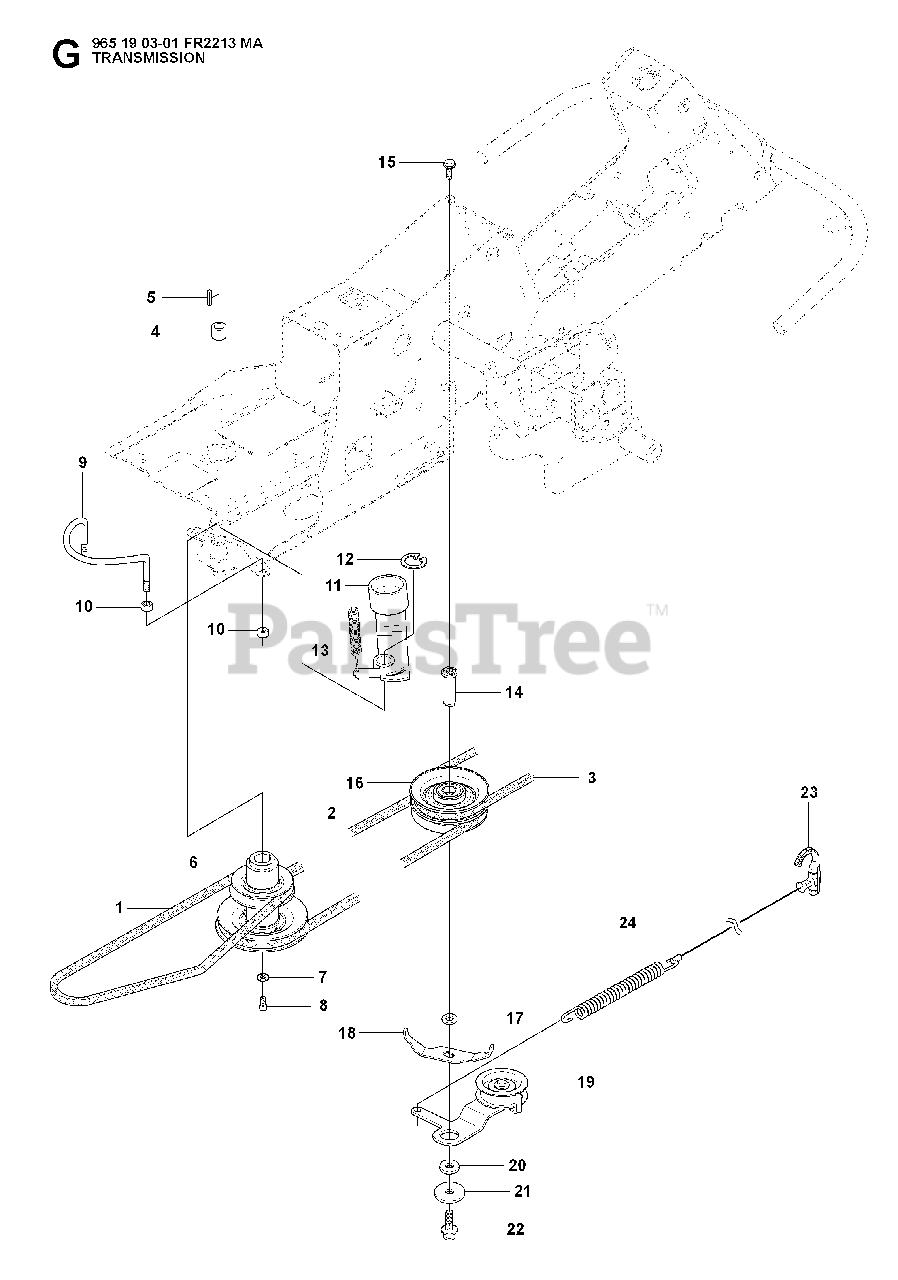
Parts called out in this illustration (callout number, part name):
2	BELT
9	BELT GUIDE
11	TENSIONER
12	RETAINING RING SGA 25
14	SHAFT
18	BELT GUIDE
22	BOLT
